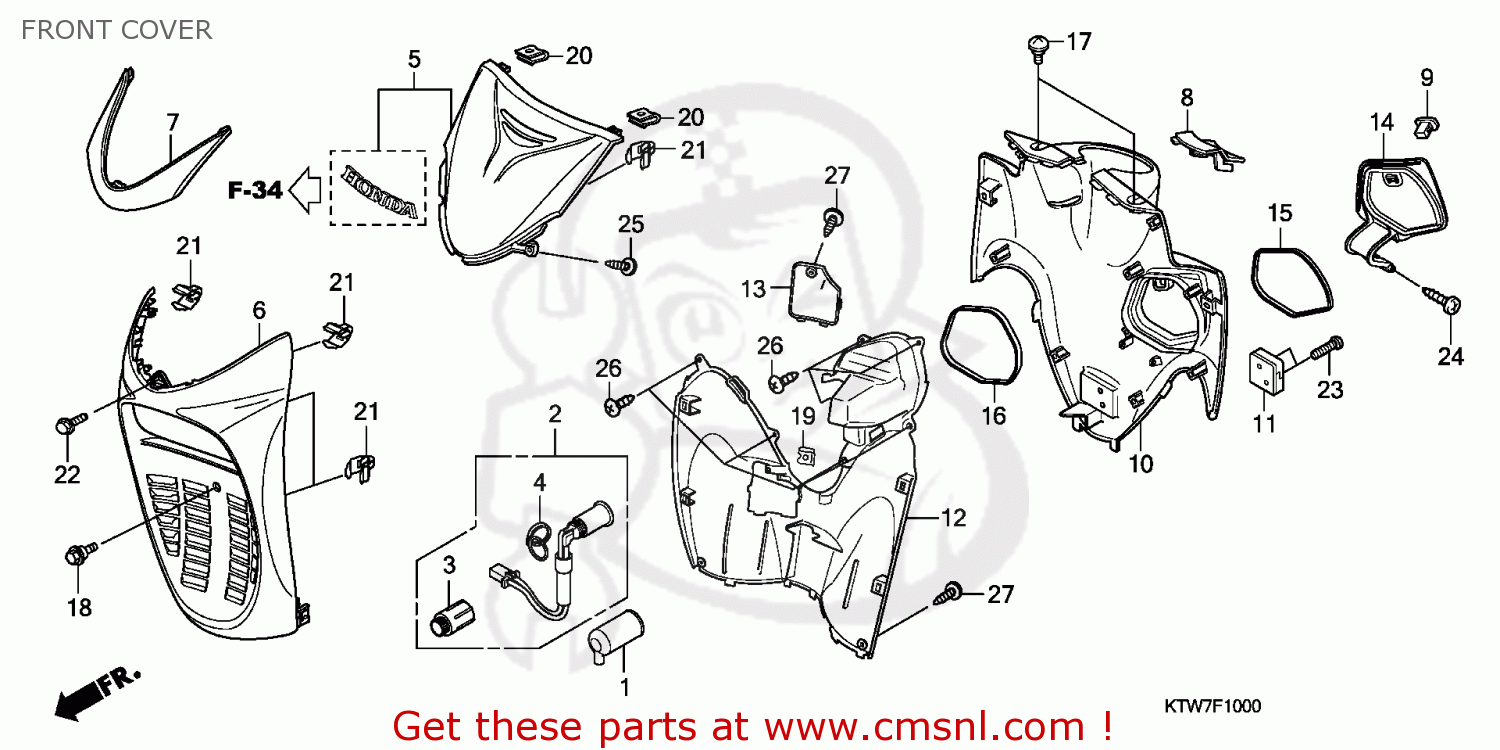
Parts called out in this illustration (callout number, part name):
1	COVER,ACC SOCKET
2	SOCKET ASSY,ACCES
3	SOCKET COVER
4	SOCKET CAP
5	SET ILLUS*NHA32M*
6	COVER,FR *NHB03M*
7	GRILL,FR
8	COVER,NEC*NHB03M*
9	OPENER,LID *NH1*
10	COVER,UPP*NHB03M*
11	HOOK,LUGGAGE
12	COVER,LOWER *NH1*
13	LID,RAD.MAIN*NH1*
14	LID,L POC*NHB03M*
15	SEAL,POCKET LID
16	SEAL,LOWER INNER
17	SCREW,6X13
18	BOLT,FLANGE,6MM
19	NUT, SPRING, 4MM
20	NUT,SPRING,6MM
21	CLIP,SNAP FIT
22	BOLT-WASHER,6X12
23	SCREW,CROSS 4X16
24	SCREW,TAP 4X12
25	SCREW,4X12
26	SCREW,TAP.4X16
27	SCREW,TAP.4X16
